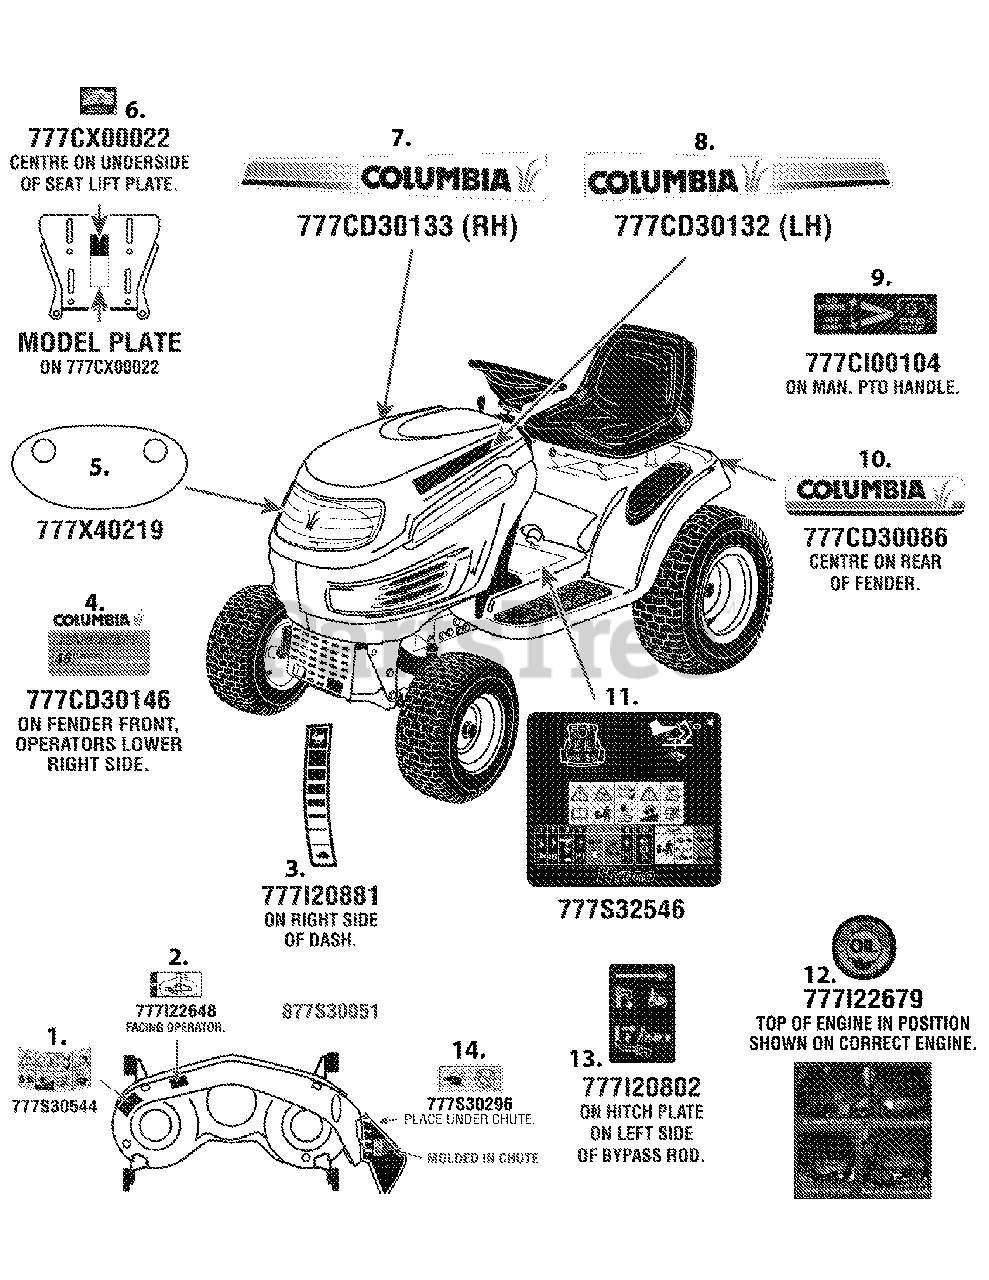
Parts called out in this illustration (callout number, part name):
1	LABEL-DECK SAFETY
2	LABEL-DECK BELT ROUTE
4	LABEL-HYD 46" FNDR
5	LABEL-LENS REFLECT
6	LABEL-MADE IN USA
7	LABEL-HOODSIDE RH STY 6
8	LABEL-HOODSIDE LH STY 6
9	LABEL-MANUAL PTO CANADA
10	LABEL-REAR FENDER COLUMBIA
11	LABEL-SAFETY/INST CANADA
12	LABEL-CHECK ENG OIL
13	LABEL-RT-99 HTCHPLT
14	LABEL:RIDER DECK: UNDERCHUTE EXP
